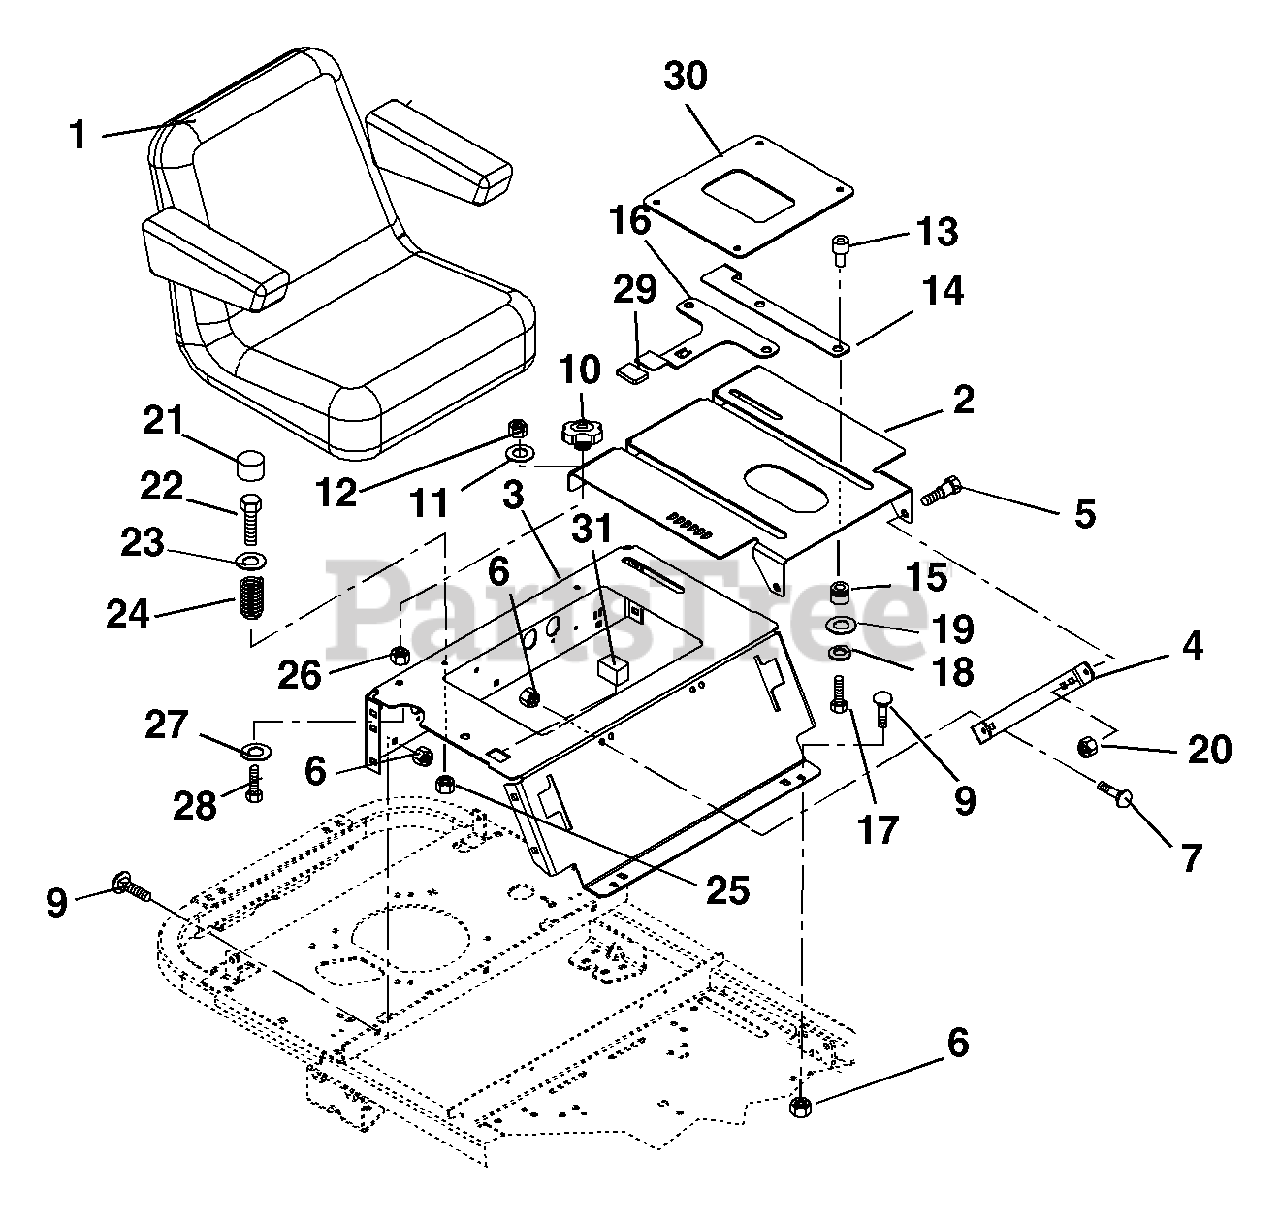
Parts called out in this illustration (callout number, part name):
1	SEAT, TS2500 MICHIGAN W/ARM.
2	SEAT PLATE
3	SEAT BOX
4	BRACKET, SEAT PLATE
5	BOLT-SHLDR .375-16X.150
6	@NUT-LK-NYL-FLG .38-16 YWZC
7	@BLT-RDHDSQNK .38-16X1.00 G5YZ
8	HOURMETER-QUARTZ 80VDCMAX
9	@BLT-RDHDSQNK .38-16X1.00 G5YZ
10	KNOB-CLAMPING, .312-18 NYLOC
11	WSHR-FL-STL .328X1.0X.094 YWZC
12	@NUT-LK-NYL .312-18 YWZC
13	SPACER, SEAT TOP
14	SEAT STOP
15	SPACER, SEAT BOTTOM
16	LEVER, SEAT ADJUSTMENT
17	@BLT-HEX .31-18X2.25 GR5 YWZC
18	@WSHR-LK .31X.078 REG YWZC
19	@WSHR-FL-STL.312X.734X.065 YWZ
20	@NUT-LK-TOP-FLG .38-16 YWZC
21	HUB CAP
22	@BLT-HEX .31-18X1.00 GR5 YWZC
23	@WSHR-FL-STL.344X.688X.065YWZC
24	SG. COMP 2.9L X 2.02OD 200LB
25	@NUT-LK-NYL-FLG .31-18 YWZC
26	@NUT-SPNLK-FLG .312-18 YWZC
27	WSHR-FL-STL .505X1.00X.062YWZC
28	@BLT-RDHDSQNK .31-18X3.50 G5YZ
30	SEAT SUPPORT PLATE
31	PLUG, HOUR METER
